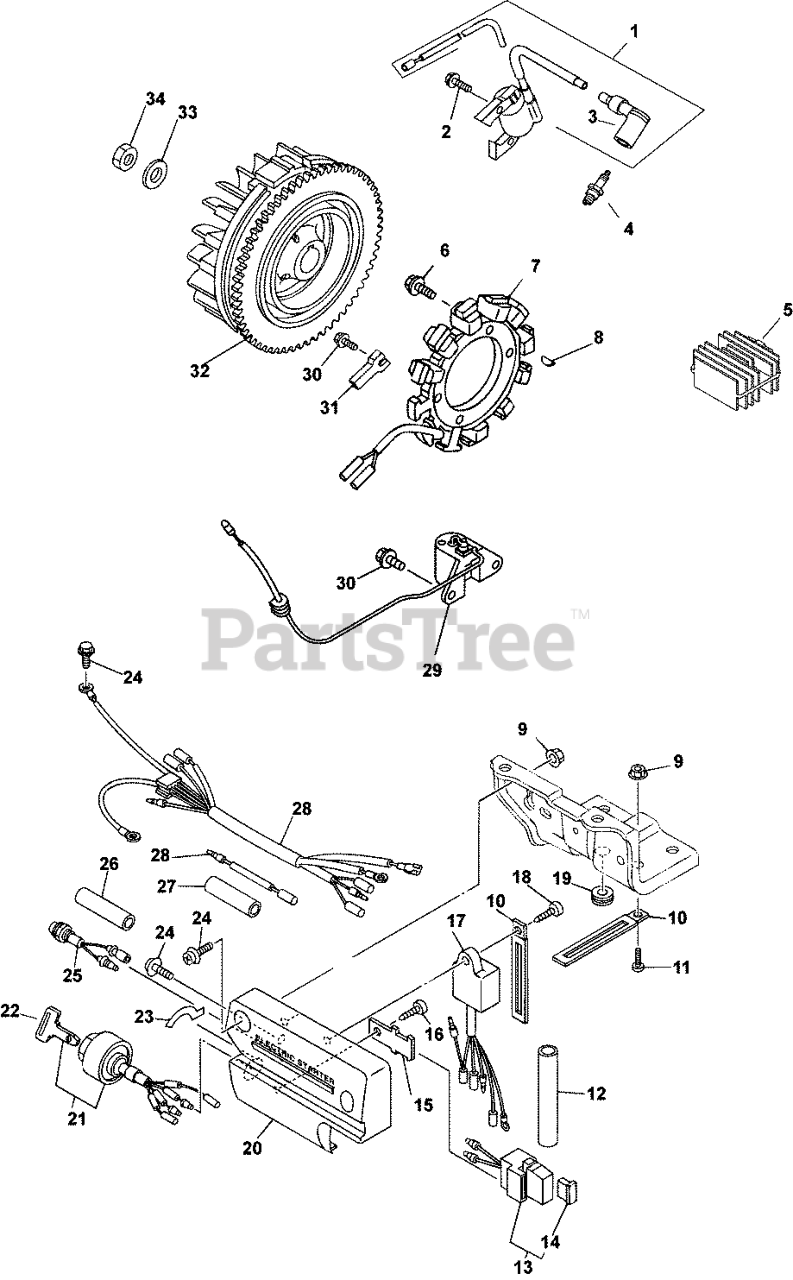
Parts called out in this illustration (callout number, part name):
1	KIT, IGNIT MODULE (600 SERIES)
3	CAP ASSEMBLY
4	SPARK PLUG
5	REGULATOR/RECTIFIER
6	SCREW (STATOR) 8.5
7	STATOR, 600 SERIES
8	KEY, WOODRUFF
9	NUT, STOP SWITCH
11	SCREW, STOP SWITCH
12	SLEEVE, WIRE
13	FUSE HOLDER
16	SCREW, TAPPING
17	OIL SWITCH ASSEMBLY -USE 63 099 03-S
20	PANEL, 600 SERIES
21	KEYSWITCH, 600 SERIES
22	KEY, IGNITION
23	DECAL, IGNITION
24	SCREW, BIND
25	OIL LIGHT
26	SLEEVE, WIRE
27	SLEEVE, WIRING
28	LEAD, 600 SERIES SPECS
29	OIL LEVEL GAUGE
32	FLYWHEEL - DISCONTINUED
